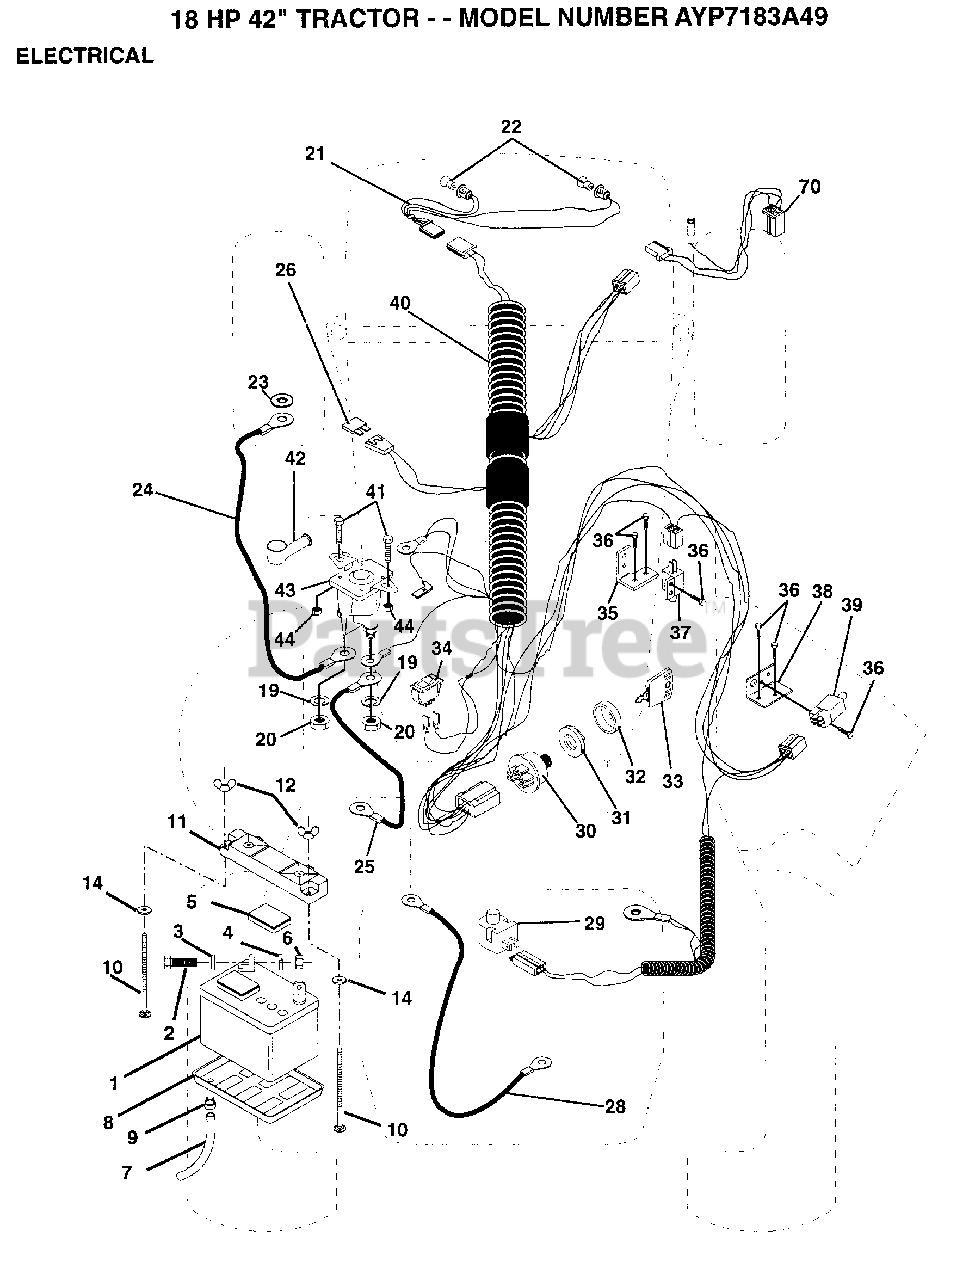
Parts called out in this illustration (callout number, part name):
2	BOLT LT
3	WASHER
4	LOCKWASHER
5	"CAP,BATTERY "
7	"DRAIN TU T, BATT"
8	"TRAY T, BATTERY"
10	BOLT
14	WASHER.3/4X1X18GA
20	NUT
21	"HARNESS,LIGHT SOC"
22	HEADLAMP BULB
23	LOCKWASHER
24	CABLE ASM.
25	CABLE-BATTERY T
26	FUSE HYT
28	CABLE T
29	SWITCH SEAT
33	KEY MLD GEN DELTA
34	SWITCH LT
35	SWITCH BRACKET
36	SCREW
37	SWITCH-INTER. GT
38	BRACKET LT
39	SWITCH INTERLOCKT
40	HARNESS IGN DASH
41	BOLT HXHD FIN
44	NUT HXKEP 1/4X20
70	HARNESS ENG DUAL
